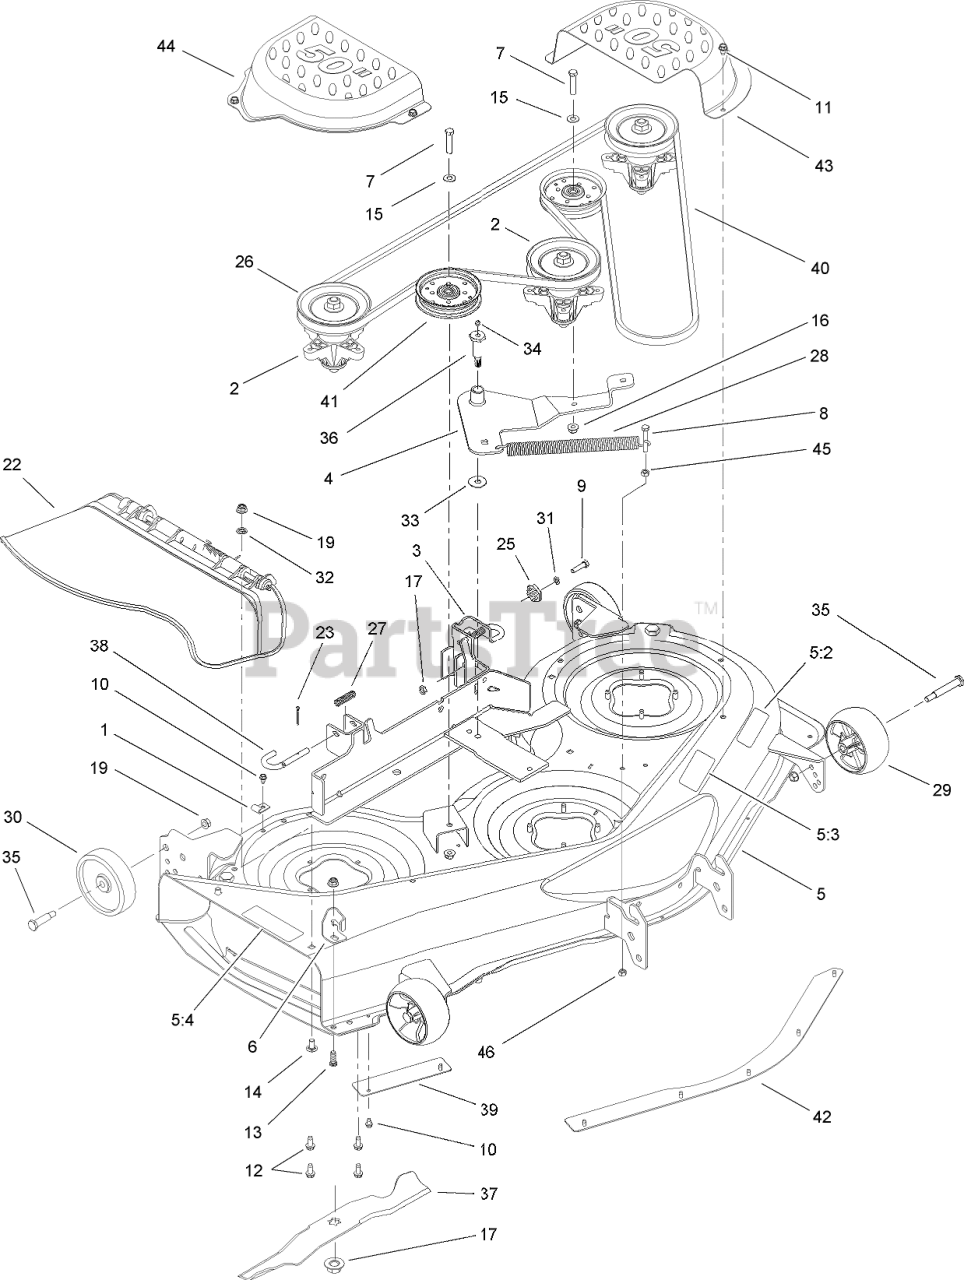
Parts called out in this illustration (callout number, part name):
1	BRACKET-RETAIN, HOOK
2	SPINDLE ASM
3	LH HANGER BRACKET ASM
4	IDLER ASM
5	DECK AND DECAL ASM
5:2	DECAL-DANGER, DECK
5:3	DECAL-BELT ROUTING, DECK
5:4	DECAL-DANGER
6	STOP-CHUTE
7	SCREW-HH
8	SCREW-HH, TAP
9	SCREW-HH
10	SCREW-HWHTF
11	SCREW-HH, TAP
12	SCREW-HWH
13	SCREW-HH
14	BOLT-CARR
15	WASHER-FLAT
16	NUT-LOCK, FLANGE
17	NUT-LOCK, FLANGE
19	NUT-LOCK, FLANGE
22	CHUTE ASM
23	PIN-COTTER
25	GEAR-ADJUSTMENT, DECK
26	PULLEY-DECK
27	SPRING-COMPRESSION
28	SPRING
29	WHEEL-DECK, FRONT
30	WHEEL-DECK, REAR
31	WASHER-LOCK
32	RETAINER-BOLT
33	WASHER-FLAT
34	FITTING-GREASE
35	BOLT-SHOULDER
36	BOLT-SHOULDER
37	BLADE-17.90 INCH
38	PIN-HANDLE, DECK RELEASE
39	SKIRT-RH
40	BELT-V, TYPE B
41	PULLEY-IDLER
42	SKIRT-CENTER
43	COVER-BELT, LH
44	COVER-BELT, RH
45	NUT-HEX
46	NUT-LOCK, FLANGE
